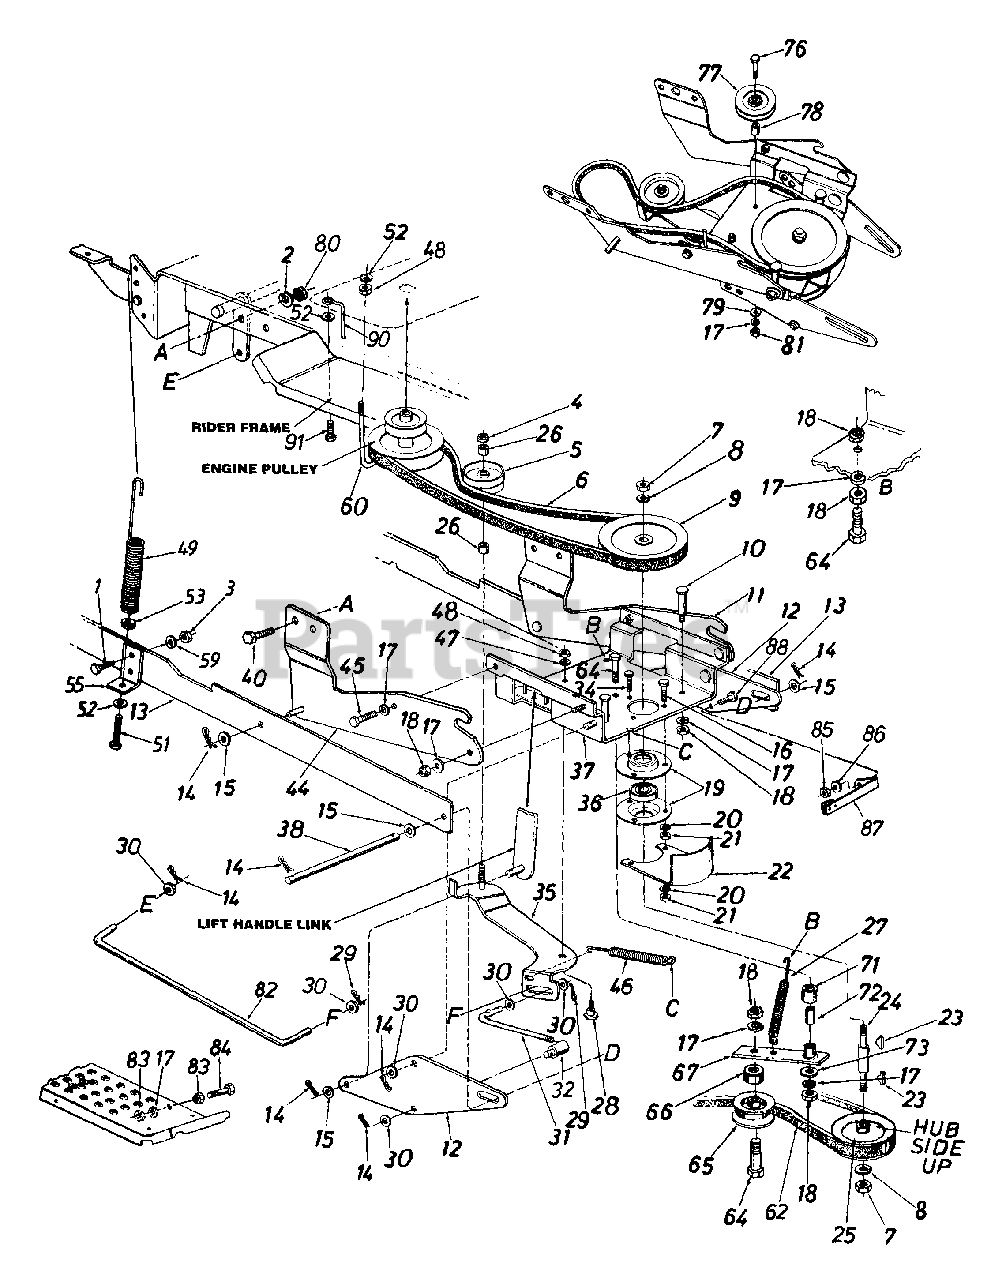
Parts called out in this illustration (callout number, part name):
1	Hex Bolt 1/4-28 x 1" Lg. Grade 5
2	L-Wash. 1/4" I.D.
3	Hex Nut 1/4-28 Thd.
4	Hex Cent. L-Nut 3/8-16 Thd.
5	Idler Pulley
6	V-Belt
7	Hex Jam Nut 5/8-11 Thd.
8	L-Wash. 5/8" I.D.
9	Pulley .627" I.D. x 6.5" O.D.
10	Shoulder Bolt
15	Fl-Wash.
16	Hex Bolt 5/16 x 1.25" Lg.
17	L-Wash. 3/8" I.D.
18	Hex Jam Nut 3/8-16 Thd.
19	Bearing Housing
20	L-Wash. 5/16" I.D.
21	Hex Nut 5/16-18 Thd.
22	Belt Guard
23	#Hi-Pro-Key 3/16" x 5/8" Dia.
24	Pulley Spindle
25	Pulley .628" I.D. x 5.56" O.D.
26	Spacer .383" I D. x .503"
27	Extension Spring 5.25" Lg.
28	Shoulder Bolt
29	Cotter Pin 3/32" Dia.
30	Fl-Wash. .385" I.D. x .87"
31	Control Rod (Clutch)
32	Ferrule
34	Hex Sems Scr. 5/16-18 x .75" Lg.
35	Clutch Idler Brkt. Ass'y.
36	Ball Bearing
37	Channel Ass'y.
38	Lift Handle Shaft
40	Hex Self-Tap Scr. 1/4-20 x .75" Lg.
44	Channel Supporting Brkt. - L.H.
45	Hex Bolt 3/8-16 x 1" Lg.
46	Extension Spring
47	L-Wash. 5/16" I.D.
48	Hex Nut 5/16-18 Thd.
49	Helper Spring
51	Hex Bolt 5/16-18 x 1.5" Lg. (Special)
52	Bell-Wash. .345" I.D. x .88"
53	Spring Insert
60	J-Bolt 5/16-18 Thd.
62	V-Belt
64	Hex Bolt 3/8-16 x 2.0" Lg.
65	Idler Pulley
66	Spacer .385" I.D. x .503"
67	Idler Arm Ass'y.
71	Spacer .380" I.D.
72	Spacer .3775" I.D.
73	Fl-Wash. 3/8" I.D. x 1" O.D.
76	Hex Bolt 3/8-16 x 2.5" Lg. (Grade 5)
77	Idler Pulley .38" I.D. x 3.06" O.D.
78	Spacer .385" I.D. x .76" Lg
79	Fl-Wash. .39" I.D. x 1-3/4" O.D.
80	Hex L-Nut 1/4-20 Thd.
81	Hex Nut 3/8-16 Thd.
82	Clutch Control Rod
83	Hex Nut 3/8-24 Thd.
84	Hex Bolt 3/8-24 x 2.25" Lg.
85	Hex Nut 3/8-16 Thd.
86	Bell-Wash. 3/8" I.D.
87	Auger Brake Brkt. Ass'y.
88	Hex Bolt 3/8-16 x 5/8" Lg.
90	Belt Guard
91	Hex Bolt 5/16-18 x .75" Lg.
